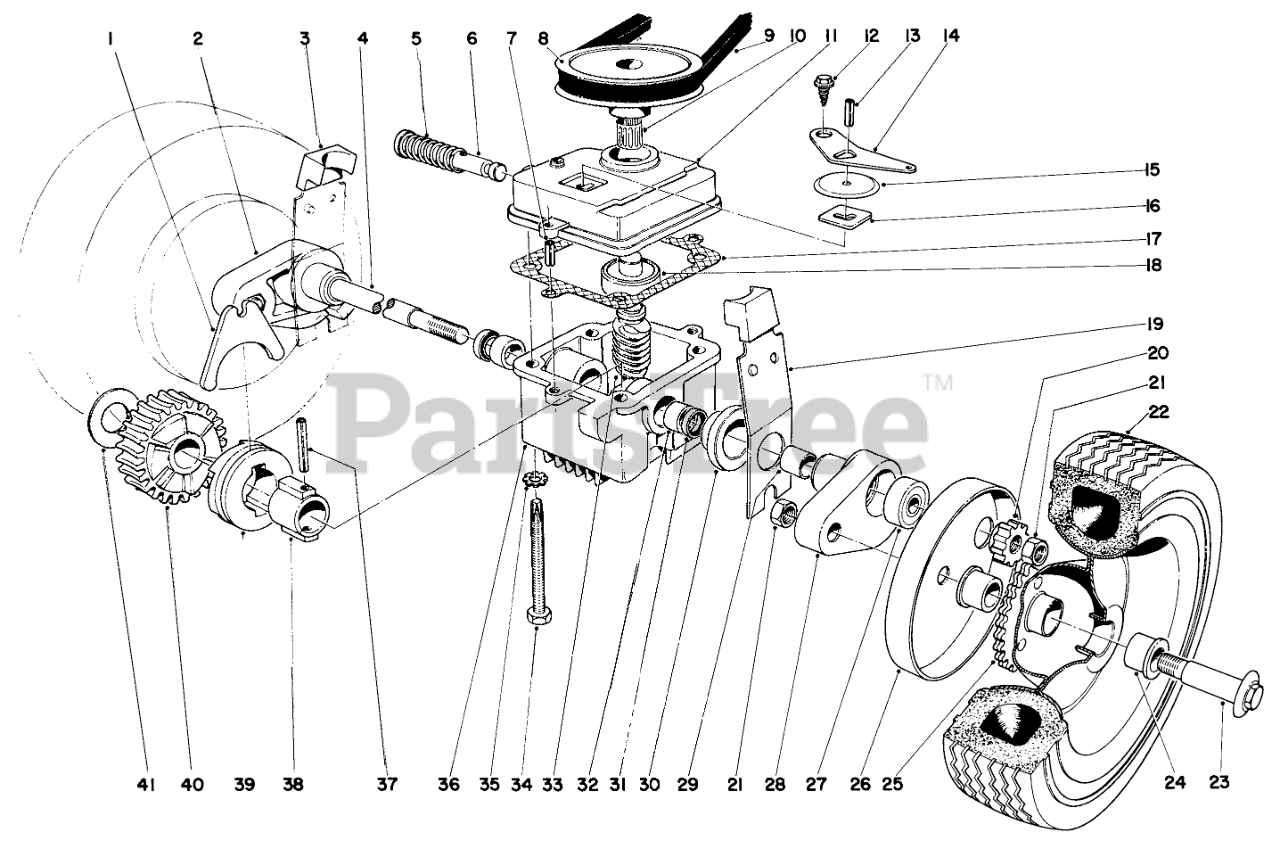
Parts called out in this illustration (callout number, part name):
1	SHIFTER FORK
2	Pivot Arm, R.H. (Incl. Ref. #27 & 29)
3	Knob
4	DRIVE SHAFT
5	SPRING
6	Shift Rod
7	3/16 X 1/2 ROLL PIN
8	PULLEY
9	V BELT
10	TOLERANCE RING
11	Cover, Gear Case (Incl.Ref. #18)
12	Screw
13	PIN-ROLL
14	SHIFTER ARM
15	TRANS DUST COVER
16	LATCH PLATE
17	GASKET
18	Bearing
19	LH SPRING ARM ASM
20	PINION GEAR
21	Nut
22	8 TIRE
23	Wheel Bolt
24	FLANGE BUSHING
25	Wheel (Incl Ref. #24)
26	WHEEL COVER
27	.375 RPP BALL BEARING
28	Pivot Arm, L.H. (Incl.Ref. #27 & #29)
29	BUSHING
30	End Cap
31	Seal
32	Bushing
33	Worm Shaft
34	Screw
35	WASHER-LOCK/EXT
36	Gear Case (Incl.Ref. #32)
37	PIN-SPRING
38	SLEEVE
39	Clutch
40	Worm Gear
41	THRUST WASHER
